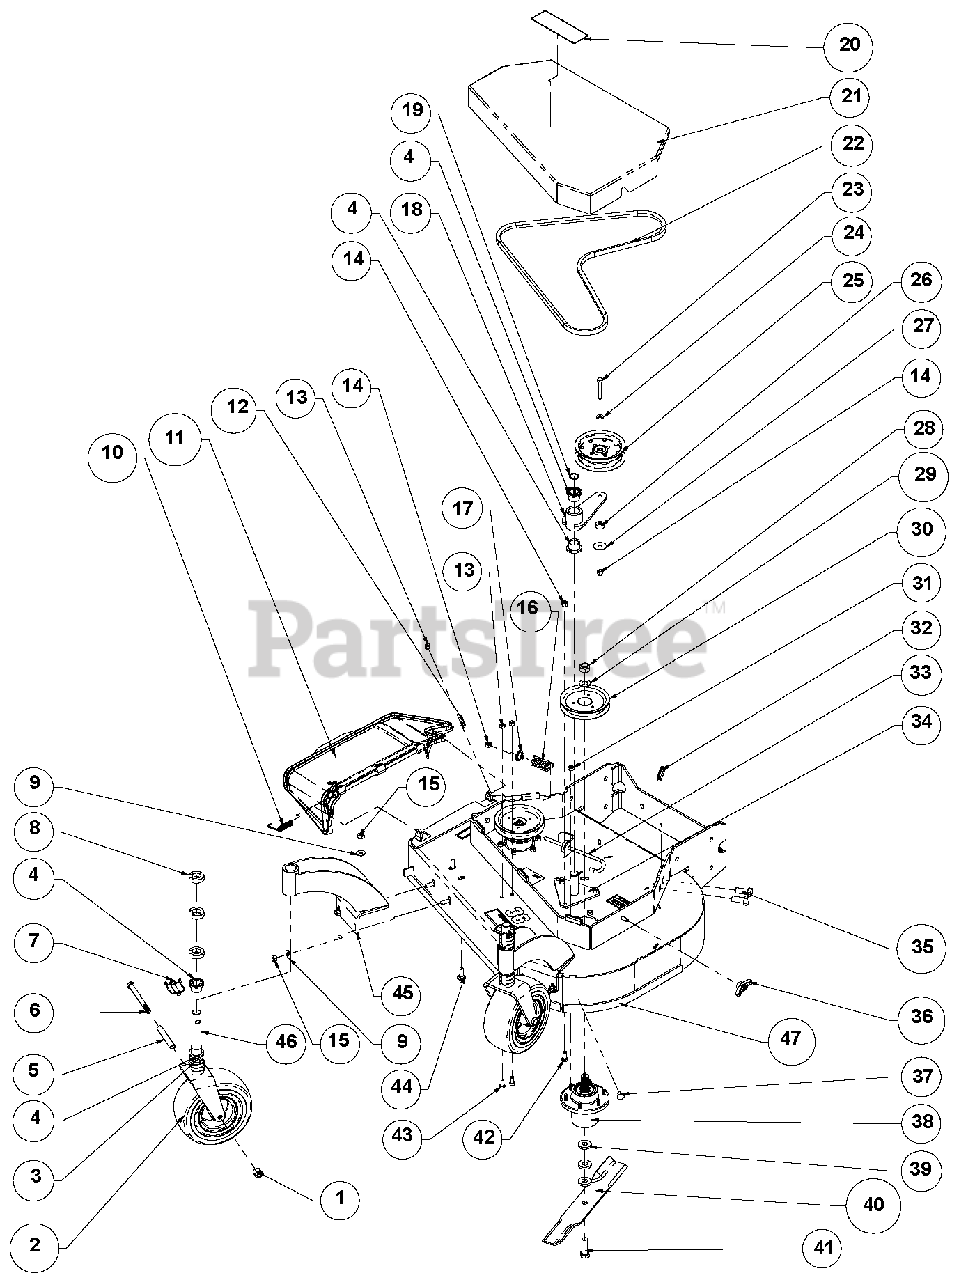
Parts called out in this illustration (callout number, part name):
1	Locknut, .50-13 Nyloc
2	Assembly, Wheel and Tire 9 x 3.5
3	Bushing, 1.03 x 1.50 x .179
4	Bearing, Flange 1.00 x 1.25 x 1.00
5	Tube, Caster Axle
6	Bolt, .50-13 x 5.50 Hex 5
7	Pin, LNC .438 x 2.00
8	C-Spacer, 1.00 x 1.77 x .500
9	Washer, .375 Regular Flat
10	Spring, Discharge Chute
11	Chute, Discharge Assembly
12	Retainer
13	Locknut, .38-16 Crown
14	Locknut, 3/8-16 Nyloc
15	Locknut, .4375-14 Crown
16	Spring, COM 1.22 x .162 x 2.50
17	Keeper, Spring
18	Weldment, Idler Arm
19	Snap Ring, 1.00 x .042 External
20	Decal-Pro 1536H
21	Weldment, 36" Deck Shield W/GRVLY
22	Belt, HB 74.3 Elbow AMD OHR
23	Bolt, .38-16 x 2.50 Hex 5
24	Washer, .406 x .813 x .065 Flat
25	Pulley, Flat 5.00X.375 W/BRG
26	Bushing, .380 x 1.00 x .410
27	Washer, .375 x 1.50 x .063 Flat
28	Locknut, .75-16 Crown
29	Washer, .75 x 1.3125 x .120
30	Pulley, Spline Spindle LSE
31	Nut, .38-16 Standard Hex 5
32	Trim, 1/4" Trim-Lok Edge
33	J-Bolt, .38-16 x 7.88
34	Weldment, Idler Pivot Mount
35	Bolt, Hex .6250-11 1.5" Grade 8
36	Knob, .38-16 Insert
37	Bolt, .38-16 x .750 Round Head Square Neck
38	Assembly, Spindle Housing
39	Washer, .630 x 1.50 x .250 Flat
40	Blade, 18.000 x .80 Lift
41	Bolt, .625-11 x 2.00 Hex 8
42	Bolt, .38-16 x 1.00 Round Head Square Neck
43	Bolt, .38-16 x .750 Hex 5
44	Bolt, .4375-14 x 1.25 Round Head Square Neck
45	Weldment, Caster Support w/Gravely Paint
46	Weldment, Caster Yoke w/Gravely Paint
47	Assembly, Gravely 36" Deck with Decal
